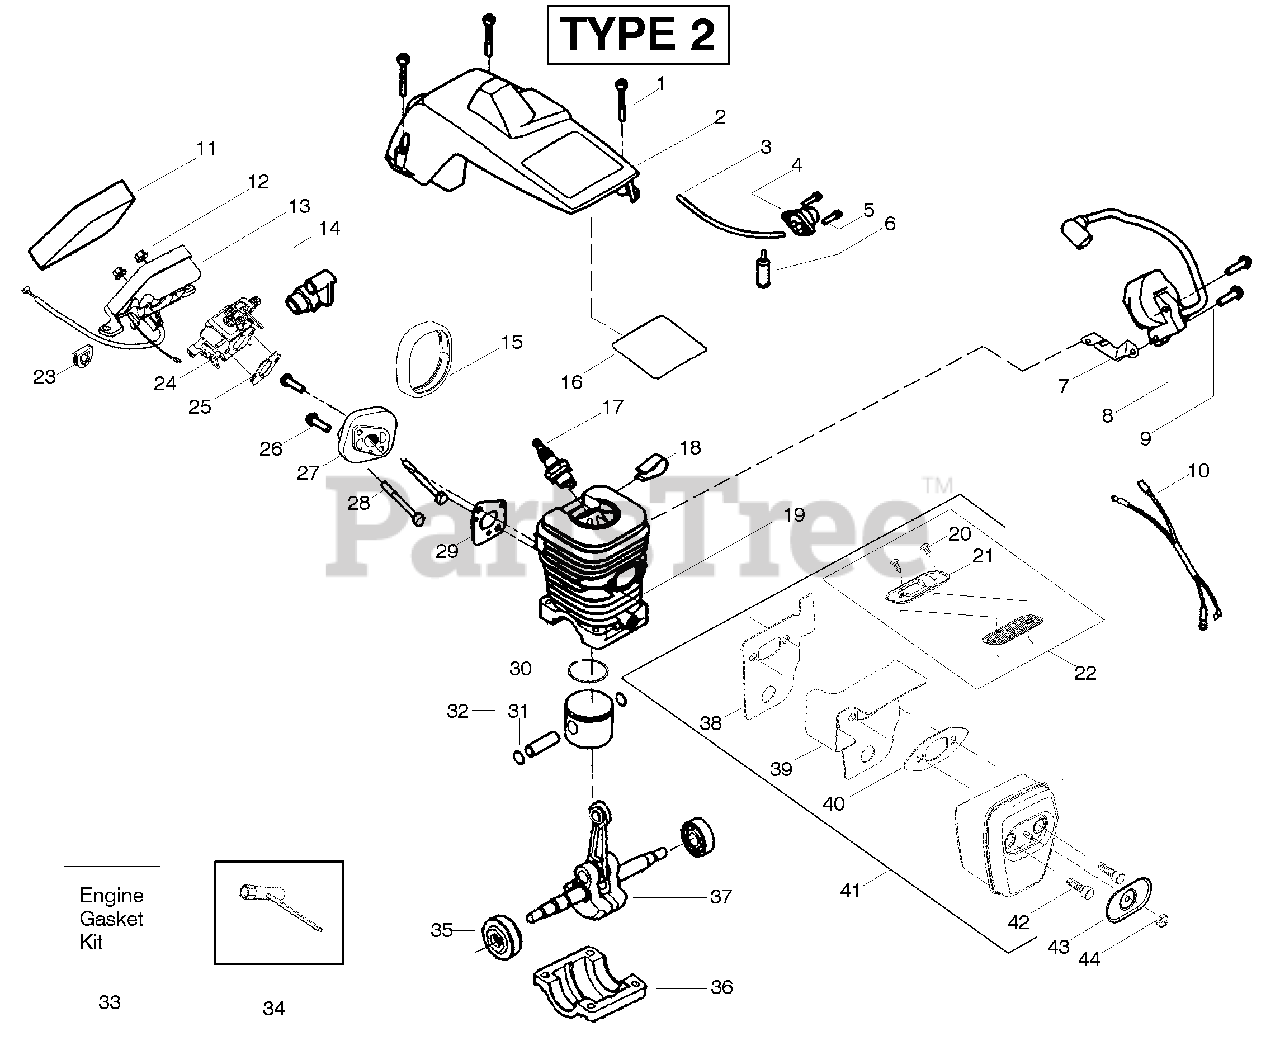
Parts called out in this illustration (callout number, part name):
2	Assy-Cylinder Shield
3	Kit-Fuel Line (Small)
4	Kit-Purge Bulb
6	Assy-Fuel Pick-up
7	Strap-Ground
8	Ignition Module
10	Assy-Wire Harness
11	Foam- Air Filter
13	Assy- Air Box
14	Grommet-Carb Adjust
15	Seal-Carb Adapter
16	Reflector-Heat
17	Spark Plug (RCJ-7Y)
18	Clip-High Tension Lead
19	Cylinder
20	Screw-Outlet cover
21	Cover - Outlet
22	Kit-Spark Arrestor
23	Grommet-Throttle Cable
24	Kit-Carburetor Zama (W-20)
24	Kit-Carburetor Walbro (WT-662)
25	Gasket-Carb. (kit)
27	Carb. Adapter
29	Gasket- Adaptor(kit)
30	Ring-Piston
31	Retainer-Piston Pin
32	Kit-Piston
33	Kit-Engine Gasket
34	Bar Wrench
35	Assy-Seal & Bearing
36	Cap-Crankcase
37	Assy-Crankshaft
38	Backplate
39	Guide-Outlet
40	Gasket-Muffler(kit)
41	Assy-Muffler
42	Bolt-Muffler
43	Cover-Bolt
44	Nut-Brass
